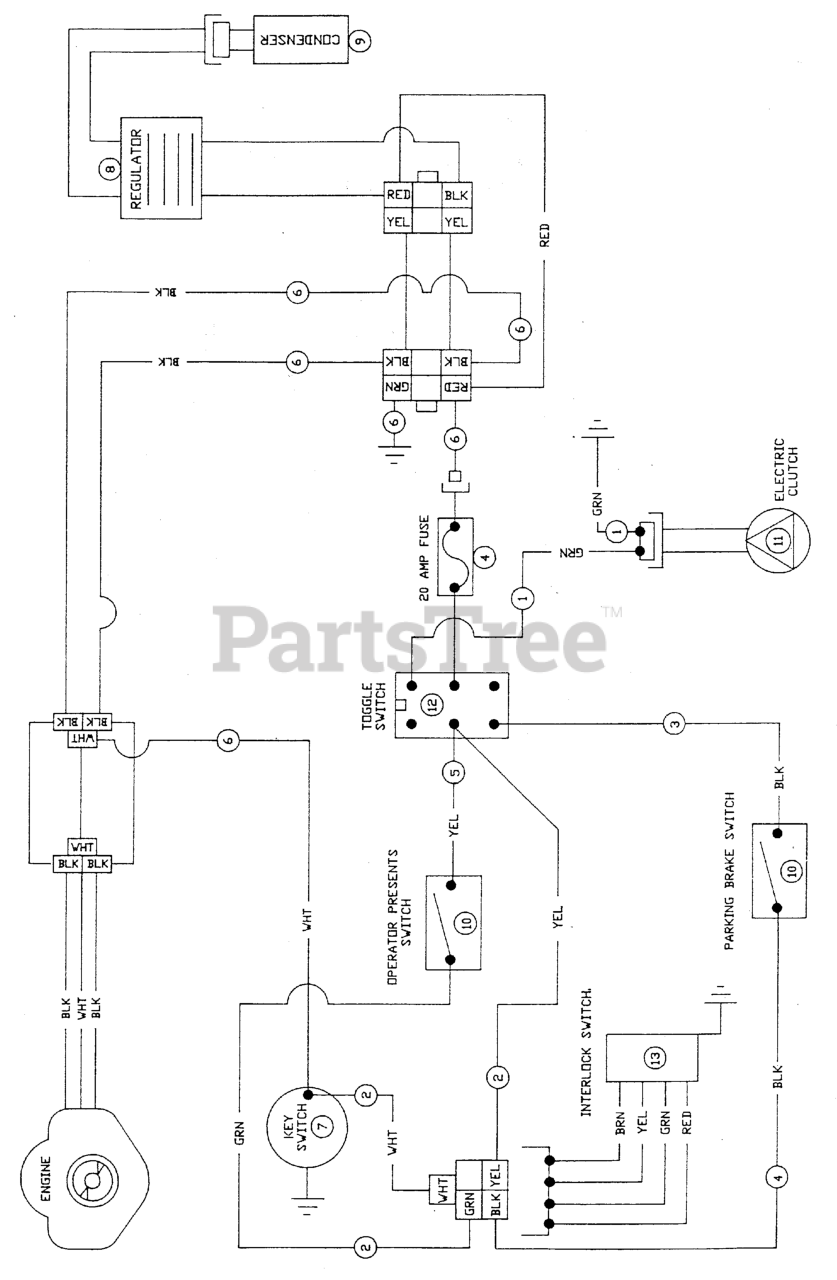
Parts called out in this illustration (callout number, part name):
1	Electric Clutch Harness
2	Interlock Harness
3	Black Wire Assembly
4	In-Line Fuse Holder
5	Yellow Wire Assembly
6	Voltage Regulator Harness
7	SWITCH, Ignition
10	SWITCH, Plunger, NO
11	CLUTCH, Electric, 1" Shaft
12	Toggle Switch
12	Switch Guard
13	Saftey Interlock
